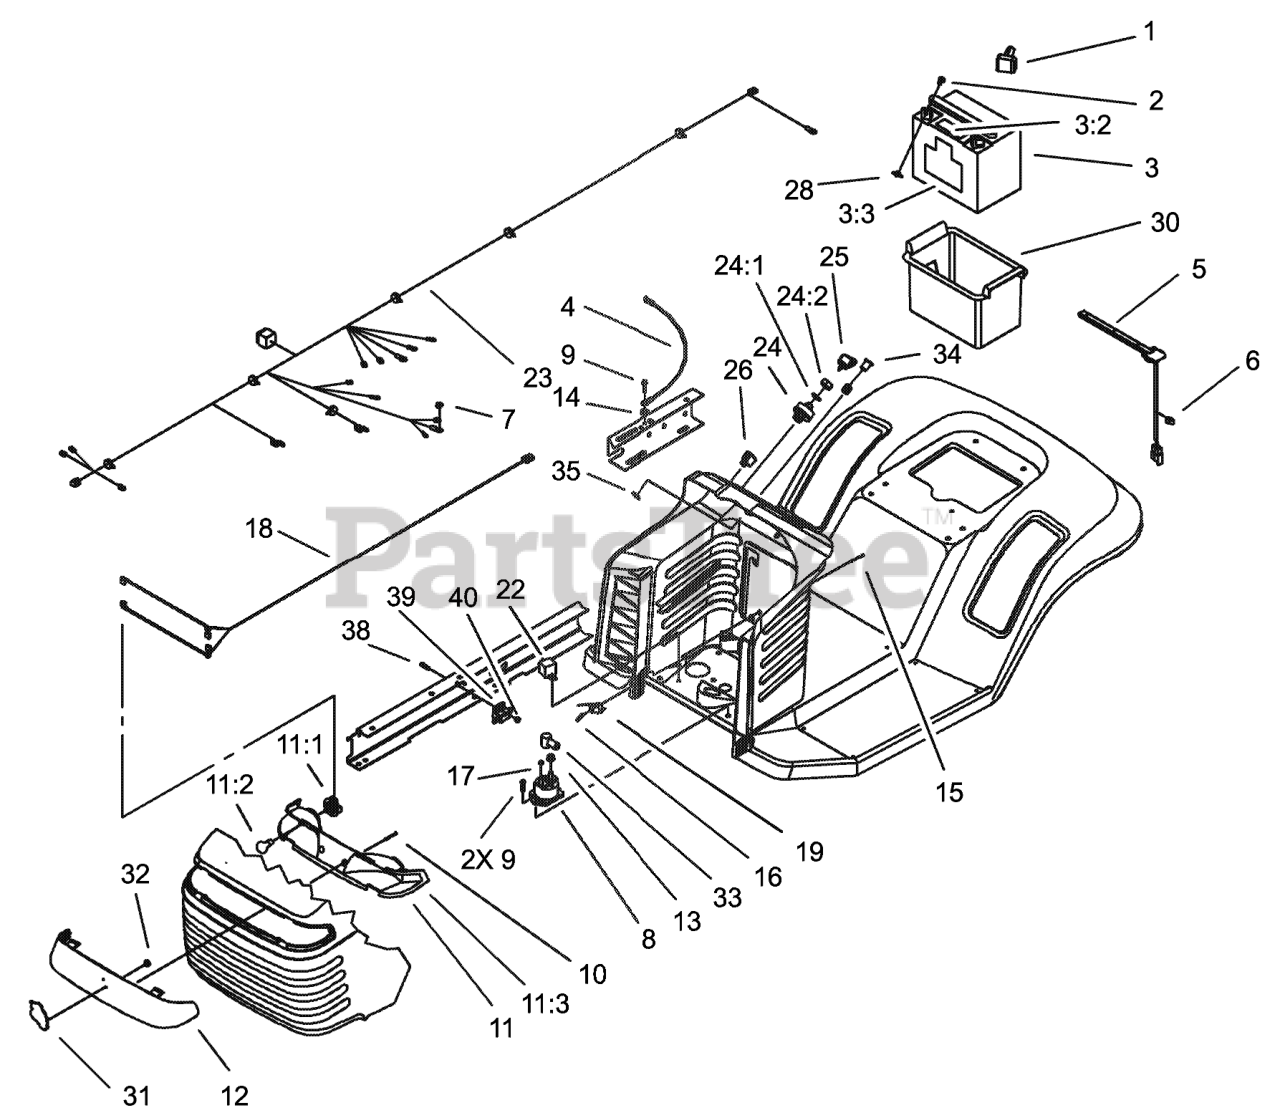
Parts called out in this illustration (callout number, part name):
1	BOOT-TERMINAL
2	SCREW-HH
3	BATTERY-155 CCA
3:2	Decal-Battery
3:3	Decal-Battery
4	WIRE ASM
5	SWITCH-SEAT
6	CLIP-RETAINER, WIRE
7	NUT-KEPS
8	SOLENOID
9	SCREW-HWH
11	HEADLIGHT REFLECTOR ASM
11:1	SOCKET-LIGHT
11:2	BULB
11:3	REFLECTOR-LIGHT
12	LENS-HEADLIGHT
13	NUT-KEPS
14	WASHER-LOCK/EXT
15	SCREW-HH
16	NUT-SPEED
17	NUT-KEPS
18	HARNESS-HEADLIGHT
19	SWITCH-MICRO
22	RELAY
23	HARNESS-WIRE
24	Key Switch ASM
24:1	WASHER-TOOTH, INTERNAL
24:2	NUT-HH
25	KEY-IGNITION
26	SWITCH-ROCKER
28	NUT-WING
30	BOX-BATTERY
31	EMBLEM-GRILLE WHEELHORSE
33	BOOT-INSULATOR, TERMINAL
34	LIGHT-INDICATOR
35	CLIP-RETAINER
38	SCREW-HSH
39	SWITCH-POLE, SINGLE
40	NUT-LOCK, NI
